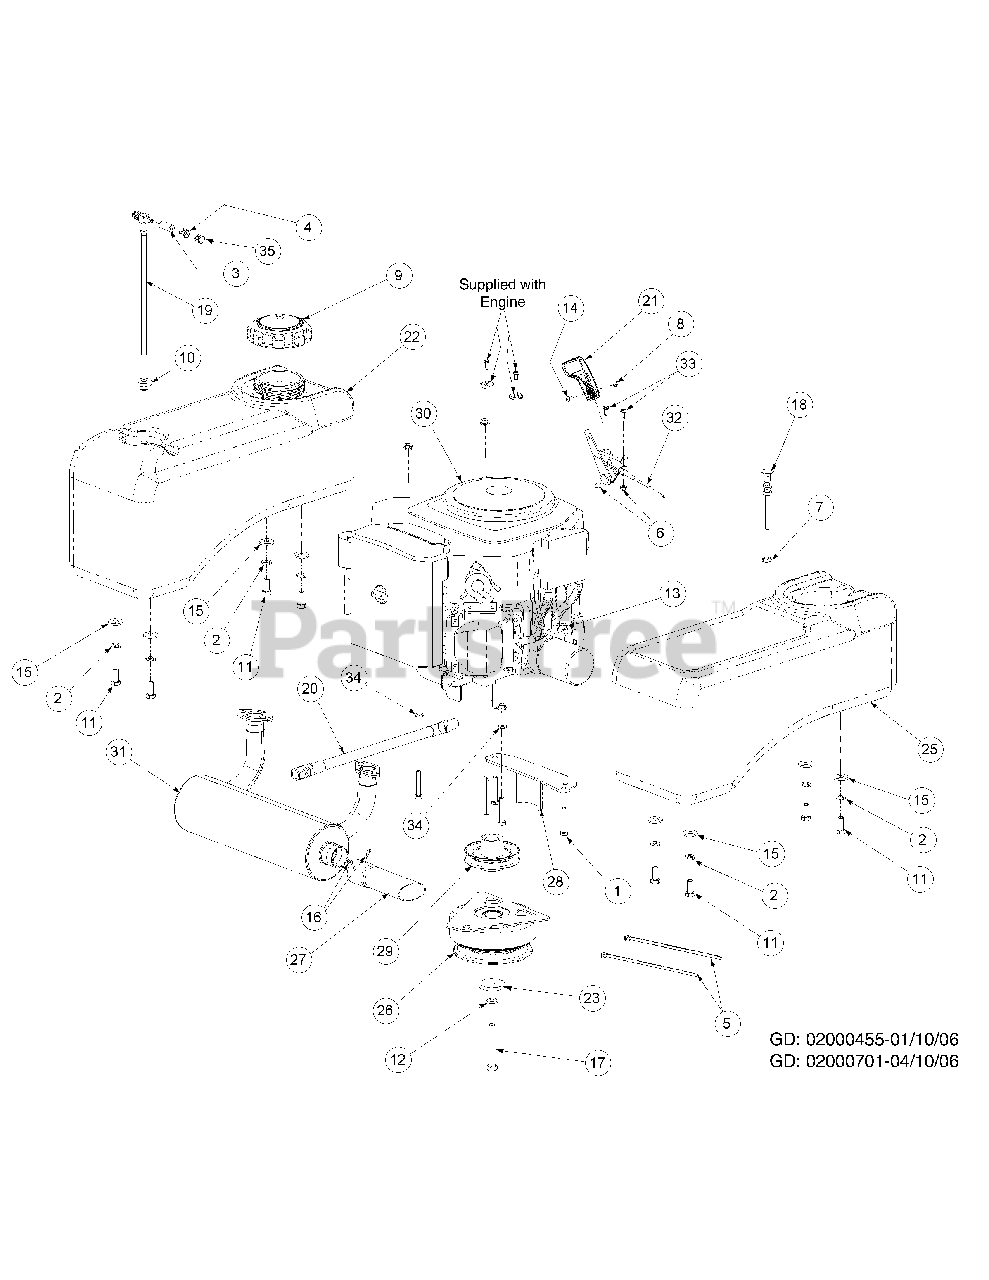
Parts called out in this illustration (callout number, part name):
1	Hex Head Cap Screw, 5/16-18 x 1-3/4
2	Lock Washer, 3/8 Zinc
3	Hose, 1/4" Fuel Line
4	Clamp, Union
5	Cable Tie, 3/16 x .05 x 7.4
6	Lock Nut, Nylon Insert, 10-32
7	Hex Jam Nut, 3/8-24
8	Nut, w/ Star Washer
9	Fuel Cap
10	Fuel Tank Groment
11	Hex Cap Screw, 3/8-16 x .88
12	Lock Washer, 7/16
13	Lock Nut, Hex Flange, 5/16-18
14	Machine Screw, 8-32 x .375
15	Flat Washer, .406 ID x 1.0 OD x .105
16	Screw, 8-32 x .375, Hex Washer
17	Hex Cap Screw, 7/16-20 x 3.0
18	Choke Cable
19	Fuel Pickup Fitting
20	Oil Drain Extension Hose
21	Throttle Control Knob
22	Fuel Tank
23	Flat Washer, 7/16 ID x 1.75 OD x .250
24	Key, 1/4 x 1/4 x 2.75
25	Utility Bin
26	Ogura DX11 Electric Clutch
27	Exhaust Pipe
28	Clutch Retainer Assembly
29	Electric PTO Engine Pulley
30	20HP Kohler Engine
31	Kohler Muffler
32	Throttle Control Cable
33	Screw, #10-32 x 0.500
34	Washer, 3/8 x .738 x .063
35	Hose Clam, 1/4-5/8, SS
